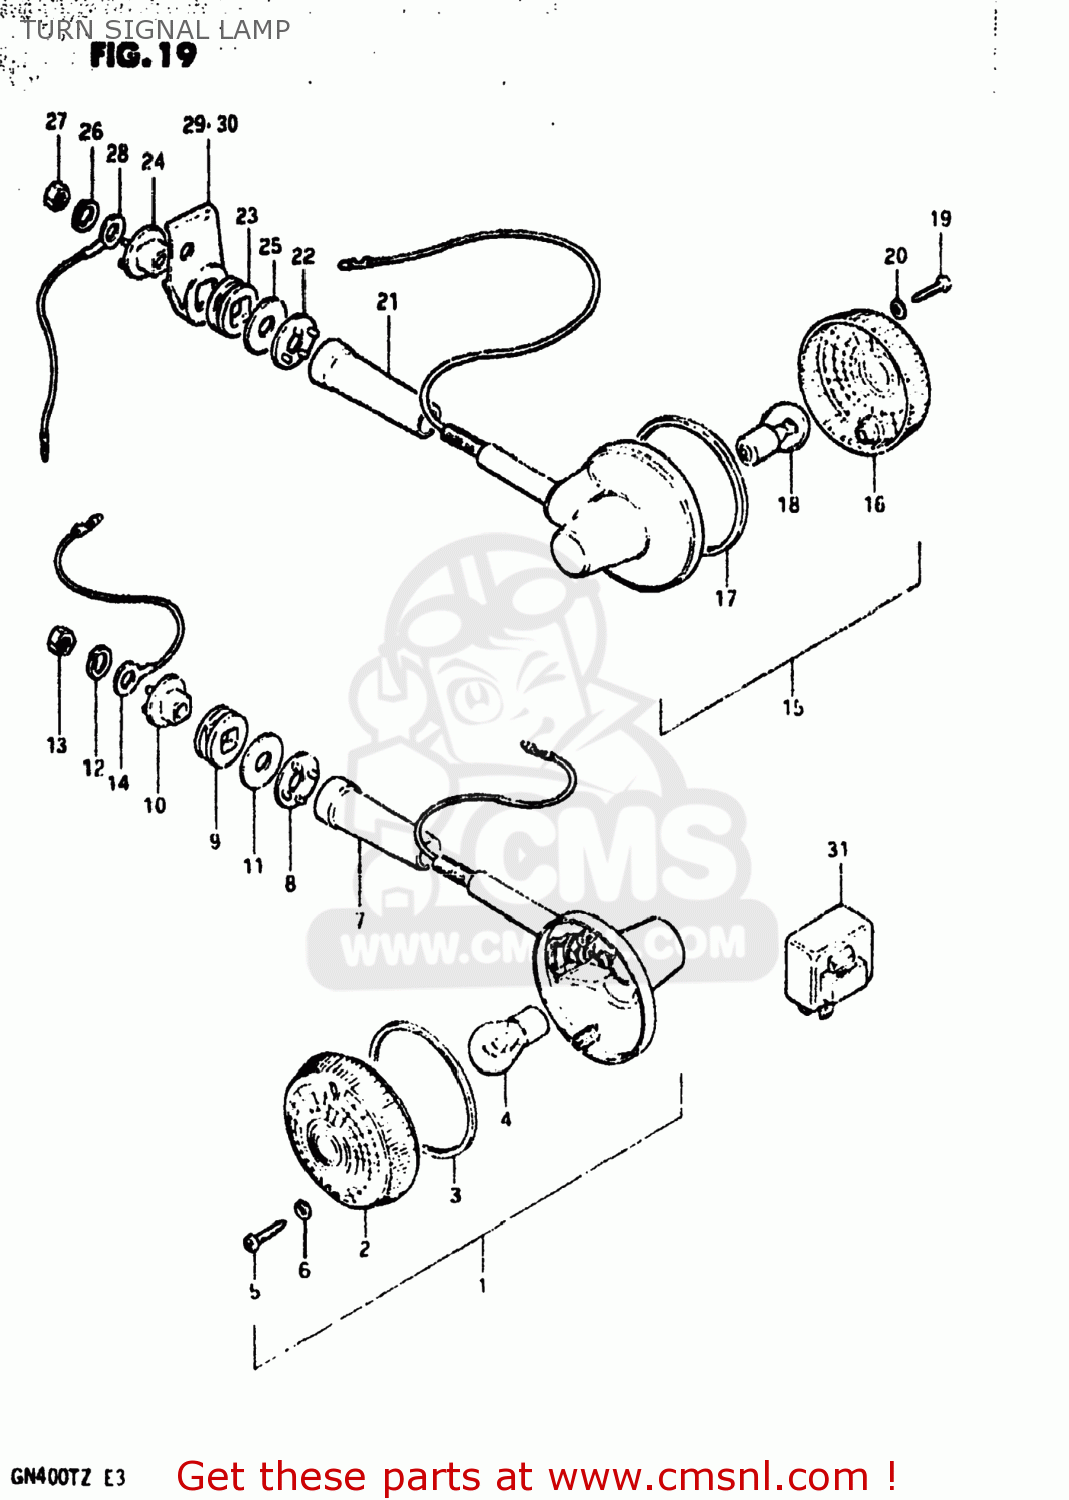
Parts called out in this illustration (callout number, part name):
1	LAMP ASSEMBLY,FRONT TURN SIGNAL
2	LENS
3	GASKET (NAS)
4	BULB(6V17W,STANLEY,A4513A)
5	SCREW
6	GASKET (NAS)
7	COVER,STAY
8	SPACER
9	CUSHION
10	SPACER
11	WASHER (10.5X30X2.3)
12	LOCK WASHER
13	NUT
14	LEAD WIRE,EARTH
15	LAMP ASSEMBLY,REAR TURN SIGNAL
16	LENS
17	GASKET (NAS)
18	BULB(6V17W,STANLEY,A4513A)
19	SCREW
20	GASKET (NAS)
21	COVER,STAY
22	SPACER
23	CUSHION
24	SPACER
25	WASHER (10.5X30X2.3)
26	LOCK WASHER
27	NUT
28	LEAD WIRE,EARTH
29	BRACKET,RR TURNSIGNAL LAMP,R
30	BRACKET,RR TURNSIGNAL LAMP,L
31	RELAY,TURN SIGNAL
